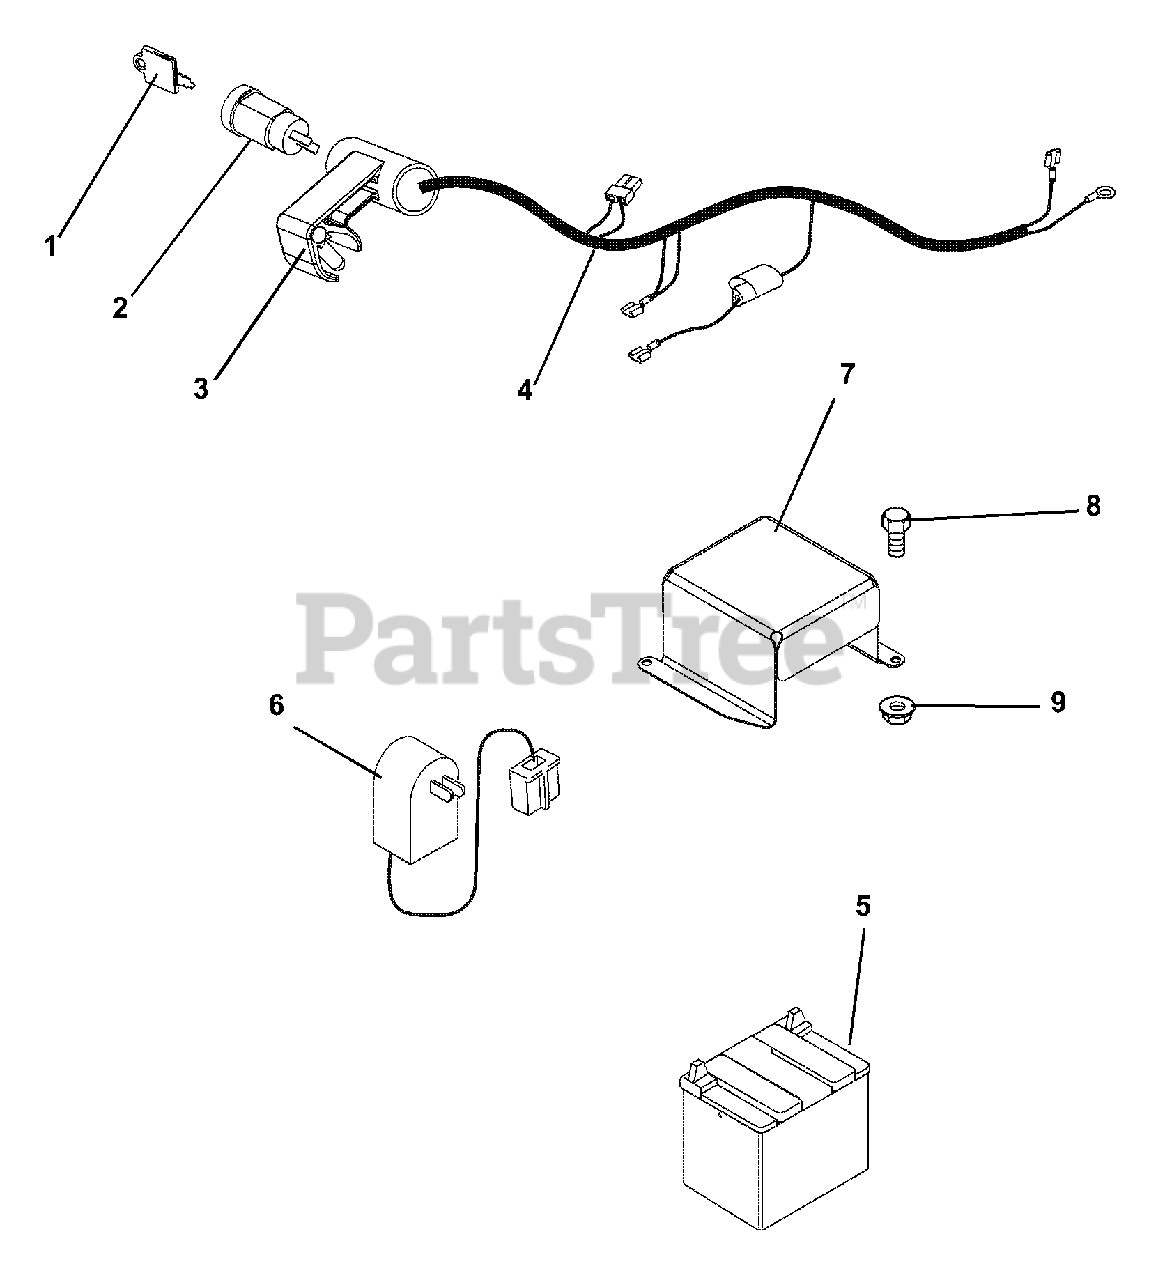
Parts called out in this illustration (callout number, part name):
2	Key, Switch
3	Housing, Switch
4	Harness, Wire
6	Battery, Charger
7	Cover, Battery
8	Bolt, Hex 8-32 x .5
9	Nut-Locking-Nylon 8-32
